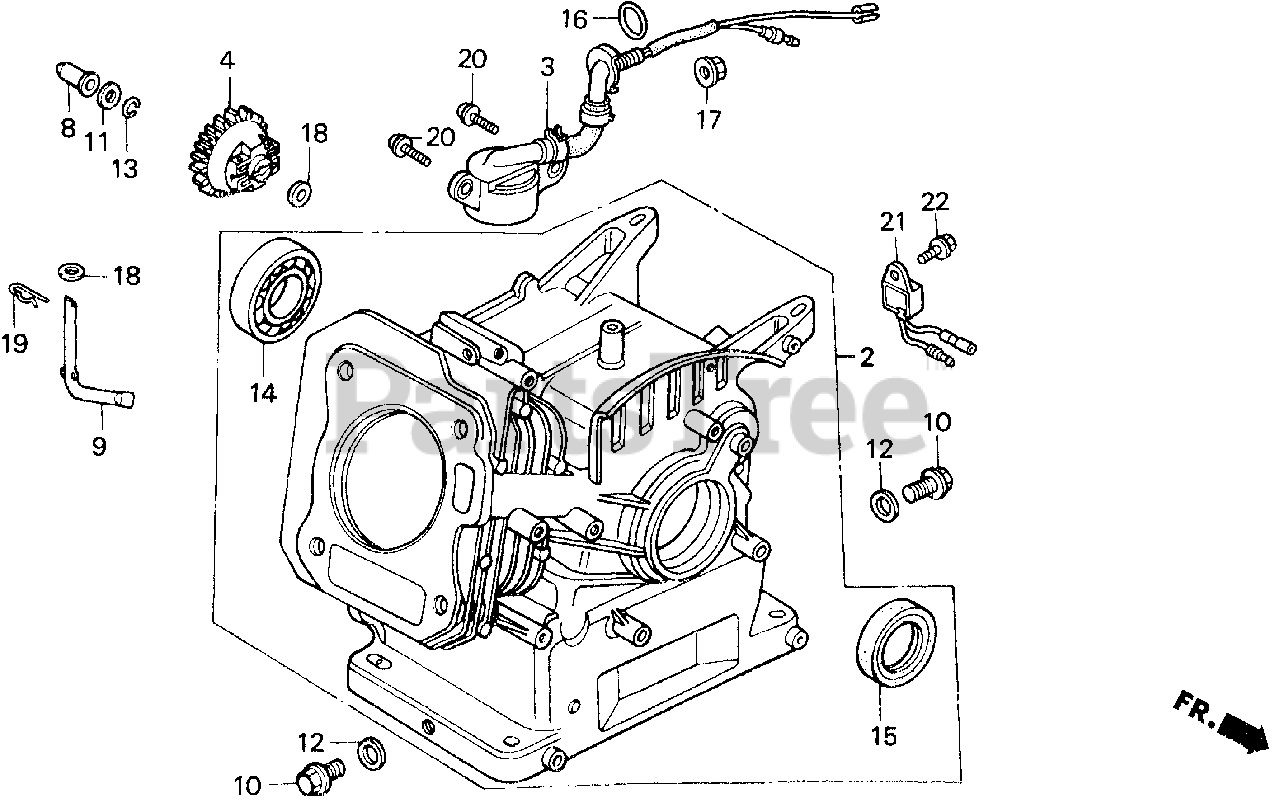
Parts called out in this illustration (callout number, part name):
2	CYLINDER ASSY. (811)
3	SWITCH ASSY., OIL LEVEL
4	GOVERNOR ASSY.
8	SLIDER, GOVERNOR
9	SHAFT, GOVERNOR ARM
10	BOLT, DRAIN PLUG
11	WASHER, THRUST (6MM)
12	WASHER, DRAIN PLUG (10.2MM)
13	CLIP, GOVERNOR HOLDER
14	BEARING, RADIAL BALL (6205)
15	OIL SEAL (25X41X6)
16	O-RING (13.5X1.5) (ARAI)
17	NUT, FLANGE (10MM)
18	WASHER, PLAIN (6MM)
19	PIN, LOCK (8MM)
20	BOLT, FLANGE (6X12)
21	ALERT UNIT, OIL
22	BOLT, FLANGE (6X8)
